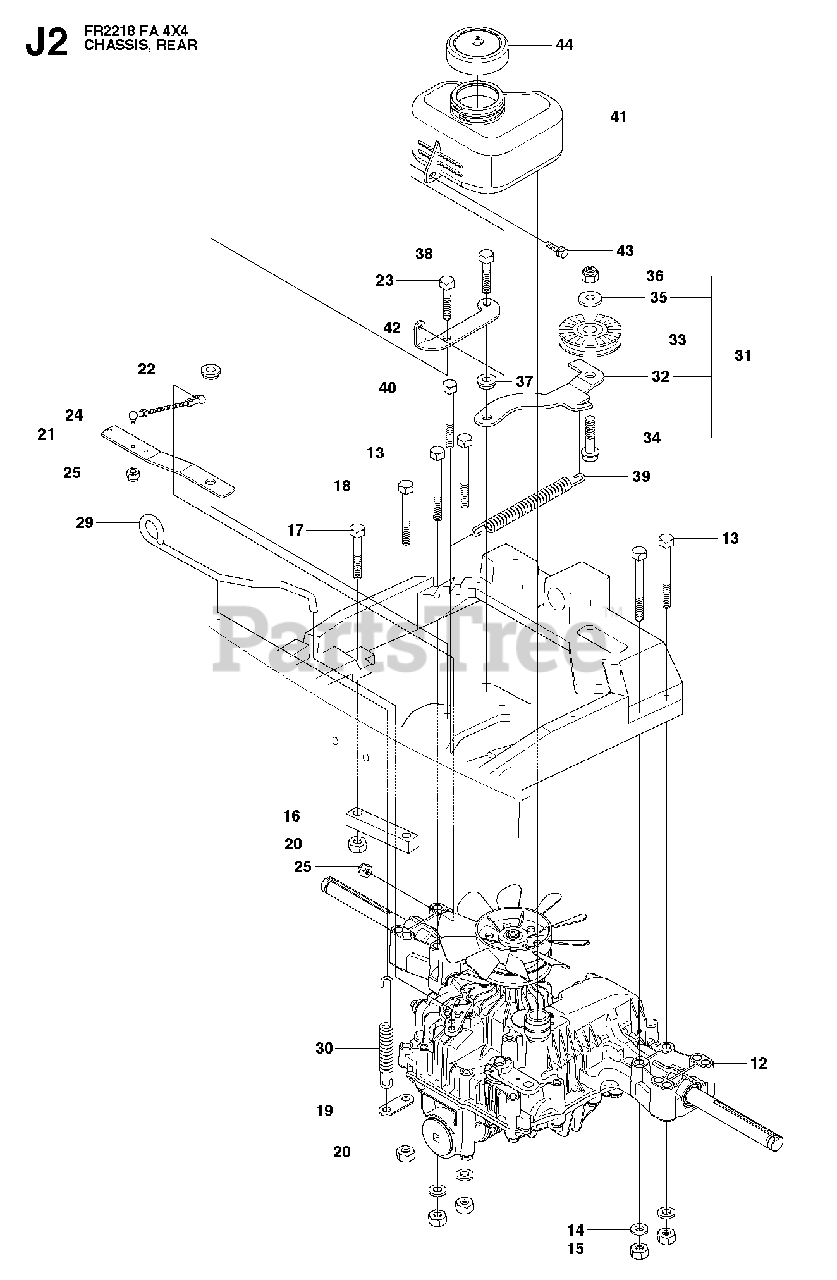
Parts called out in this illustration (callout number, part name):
12	HYDRAULMOTOR
14	WASHER BRB 8.4X17
15	NUT
19	CONNECTOR
20	NUT
22	WASHER
23	SCREW 8X20
25	LOCKNUT M5
30	SPRING
31	TENSIONER
32	TENSIONER
33	PULLEY
34	SCREW
35	SPACER
36	LOCKNUT M8
37	WASHER
38	SCREW 8X20
